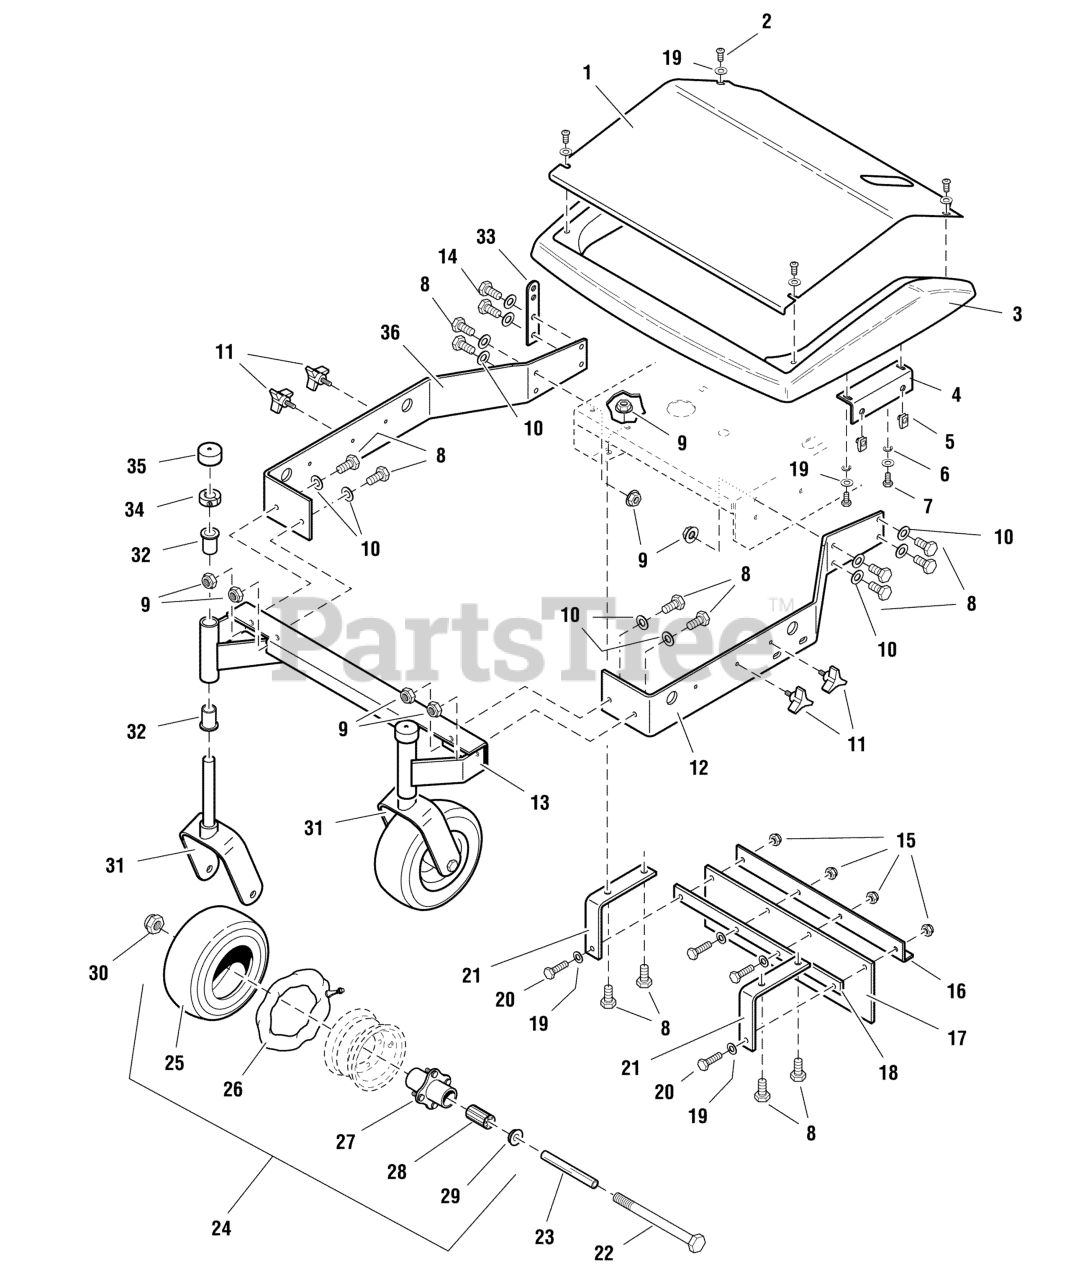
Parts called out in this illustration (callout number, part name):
2	SCREW, 1/4-20 X 1/2" ALLEN BH
3	GUARD, MOWER DECK
4	BRACKET, GUARD
5	BODY CLIP, 5/16-18-7GA MATERIAL
6	WASHER, 1/4 LOCK
7	HHCS, 1/4-20 X 0.625, GR5, ZINC/CLEAR
8	BOLT, 3/8-16 X 1" GD5 CZ
9	NUT, 3/8-16 HEX NYLOCK FLANGE
10	WASHER, 3/8 SAE
11	KNOB, PLASTIC, 5/16-18 X 1
12	RAIL, DECK FRAME - LEFT
13	CASTER MOUNT FRAME, COMPLETE
14	BOLT, 3/8-16 X 1-1/4" GD5 CZ
15	NUT, 1/4-20 HEX NYLON LOCK
16	ANGLE, DECK ARM FLAP
17	FLAP, RUBBER
18	BAR, RUBBER FLAP
19	WASHER, 1/4 SAE
20	BOLT, 1/4-20 X 1-1/4", GD5
21	BRACKET, RUBBER FLAP
22	BOLT, 1/2-13 X 5-1/2" GD5 YZ
23	AXLE, CASTER WHEEL
24	TIRE ASSM, 9 X 3.5 X 4, SILVER
25	TIRE, Front, 9 x 3.5 x 4
27	HUB & BEARING ASSEMBLY, Complete, Silver
28	BEARING, ROLLER 3/4" ID X 3.25" (ONE PER TIRE)(SV)
29	RETAINER, Bearing
30	NUT, 1/2-13 HEX NYLON LOCK
31	WELD, CASTER YOKE
32	BUSHING, FLANGE, 3/4 X 1
33	GUARD, WIRE
34	COLLAR, 3/4" SPLIT
35	CAP,VINYL, 1.375 X 1
36	RAIL, DECK FRAME - RIGHT
